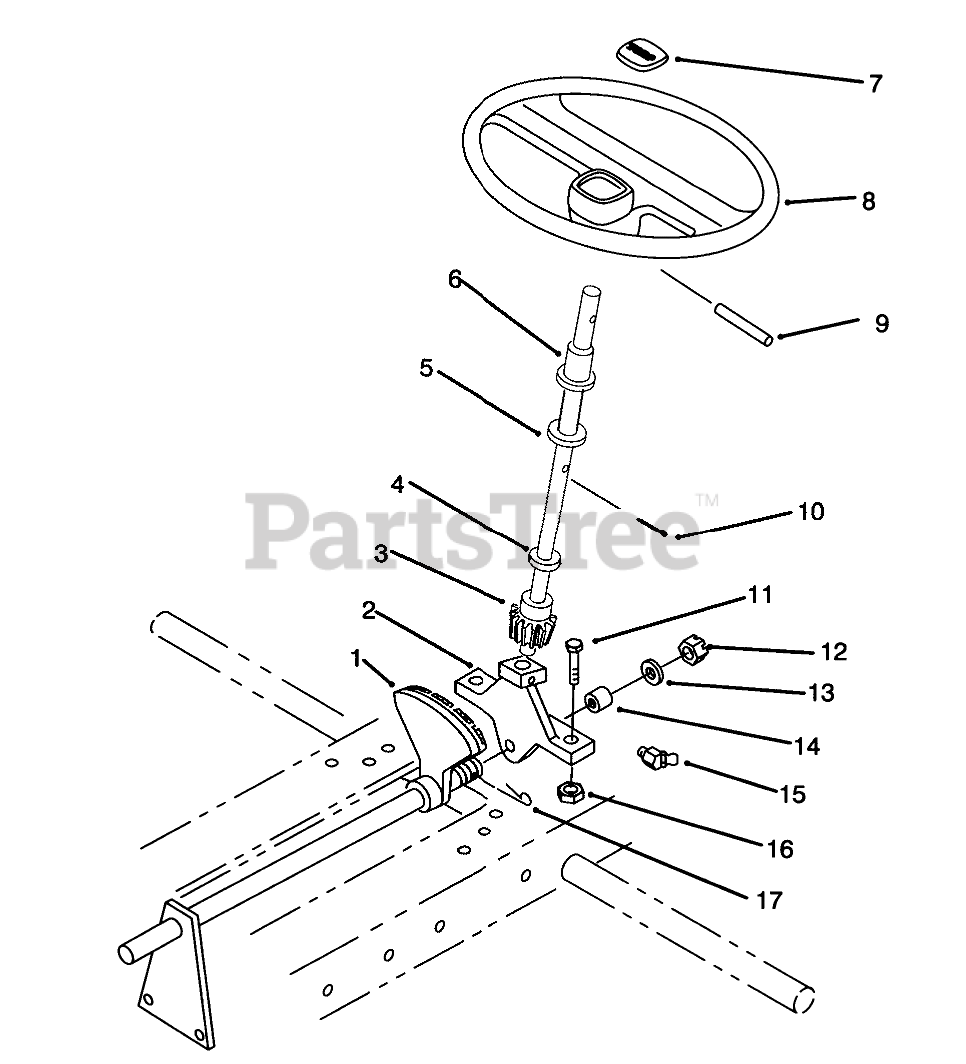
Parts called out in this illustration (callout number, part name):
1	Shaft
2	Support-Steering
3	STEERING SHAFT WA
4	O-RING
5	WASHER-SHIM
6	BEARING-FLANGED
7	STRG-WHL INSERT TORO
8	Wheel-Steering (Incl. Ref. #7)
9	PIN-ROLL
10	PIN-COTTER
11	SCREW-HH
12	NUT-HEX, SLOTTED
13	WASHER
14	BEARING-BRONZE
15	FITTING-GREASE
16	NUT-LOCK, NI
17	PIN-COTTER
